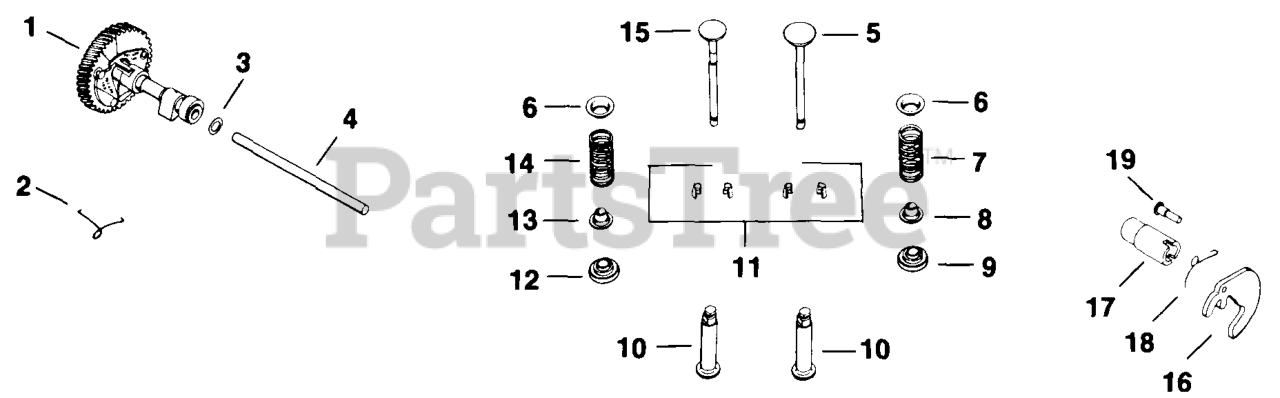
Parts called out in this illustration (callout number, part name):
1	CAMSHAFT - DISCONTINUED
2	SPRING, ACTUATING-DISCONTINUED
3	SPACER (.005")
3	SPACER (.010")
4	PIN - USE 47 380 09
5	VALVE, INTAKE - DISCONTINUED
6	RETAINER, SPRING
7	SPRING, EXHAUST VALVE-(#DSC)
8	RETAINER, VALVE SPRING
11	Kit, retainer
13	RETAINER, VALVE SPRING
14	SPRING, EXHAUST VALVE-(#DSC)
18	SPRING - DISCONTINUED
19	PIN
